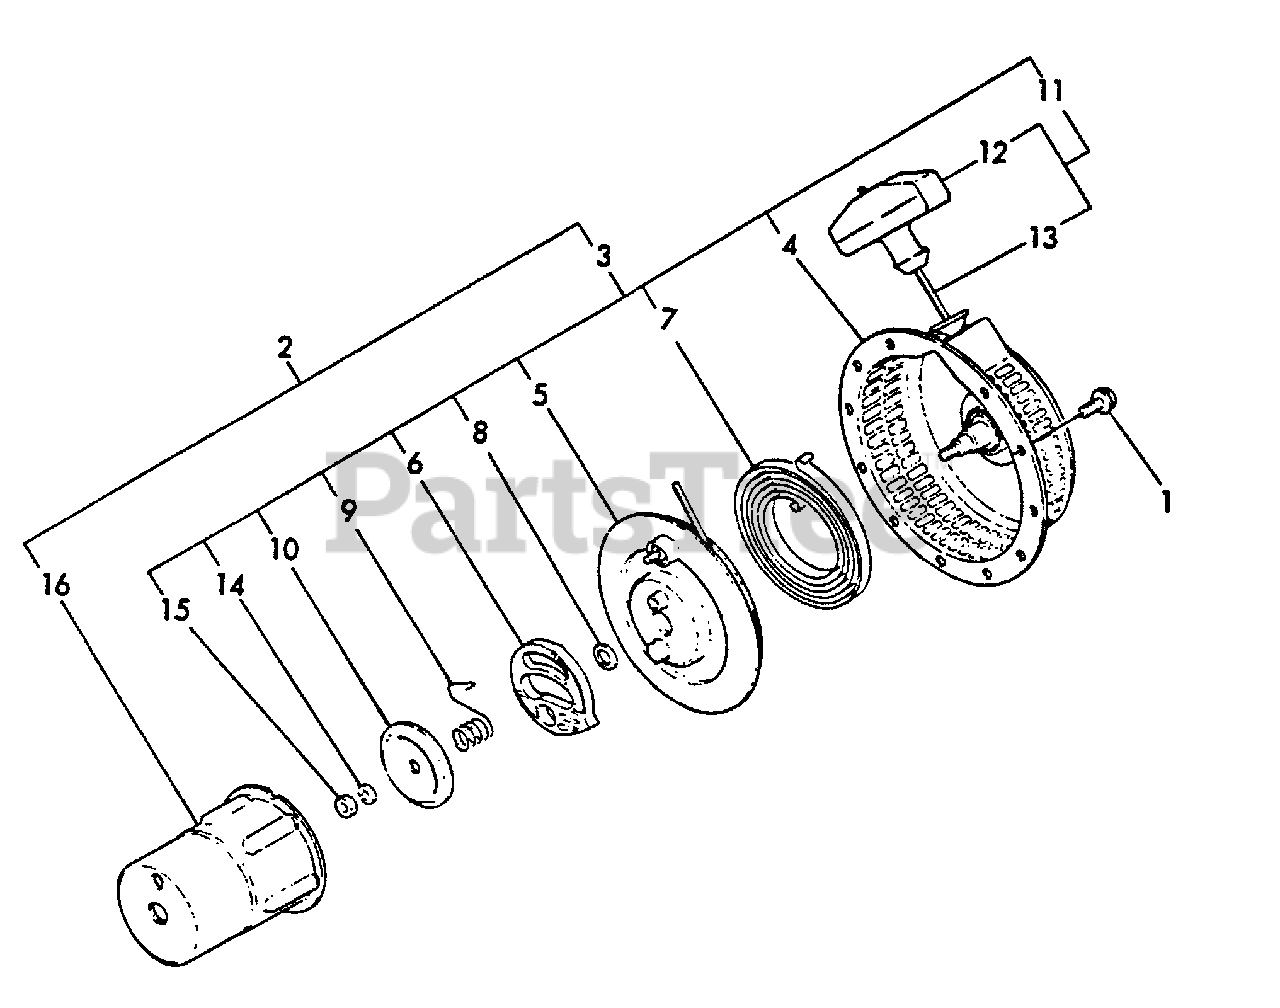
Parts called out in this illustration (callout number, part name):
1	BOLT - 6X8 -- PLATED
2	STARTER ASSY
3	STARTER ASSY
4	CASE, STARTER
5	PULLEY
8	WASHER, THRUST
9	SPRING, FRICTION
10	PLATE, FRICTION
11	STARTER ROPE ASSY
12	GRIP, STARTER
13	ROPE, STARTER
14	LOCKWASHER - 6
15	NUT - 6
16	PULLEY, STARTER
